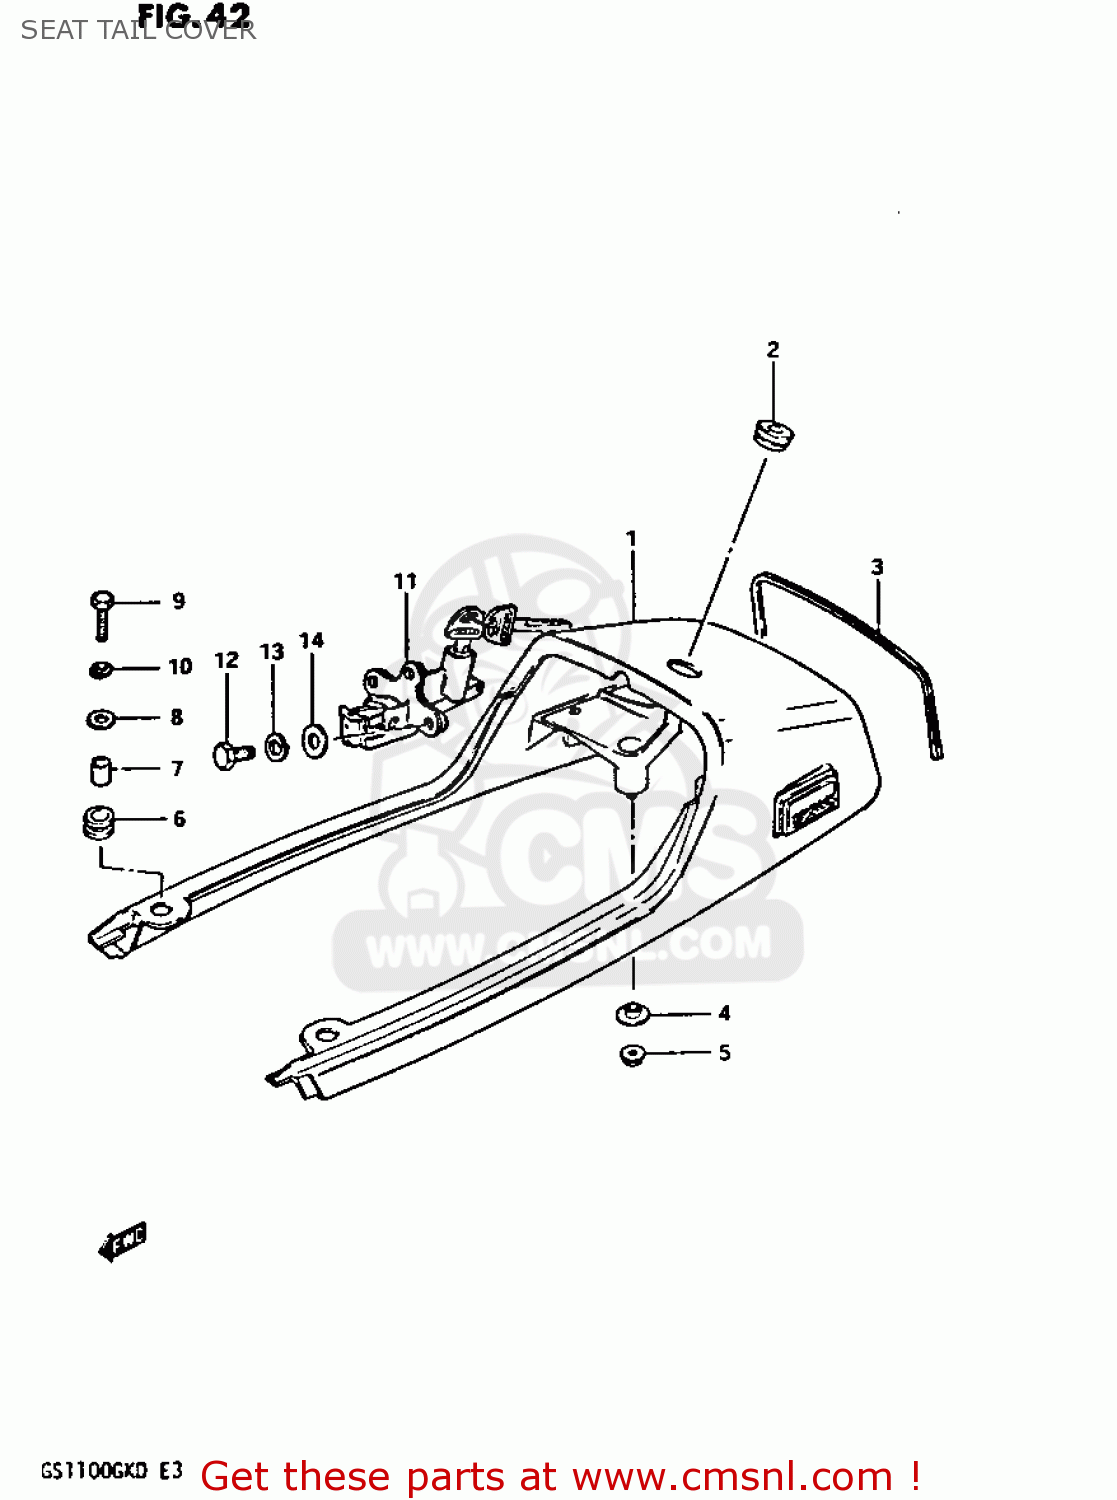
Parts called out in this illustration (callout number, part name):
1	COVER,SEAT TAIL
2	GROMMET,SEAT LOCK HOLE
3	MOLDING,SEAT TAIL COVER
4	WASHER
5	NUT 6MM
6	CUSHION
7	SPACER (7X10X12)
8	WASHER (6.5X24X1.6)
9	BOLT
10	WASHER,LOCK
11	LOCK SET,SEAT
12	BOLT
13	WASHER,LOCK
14	WASHER
